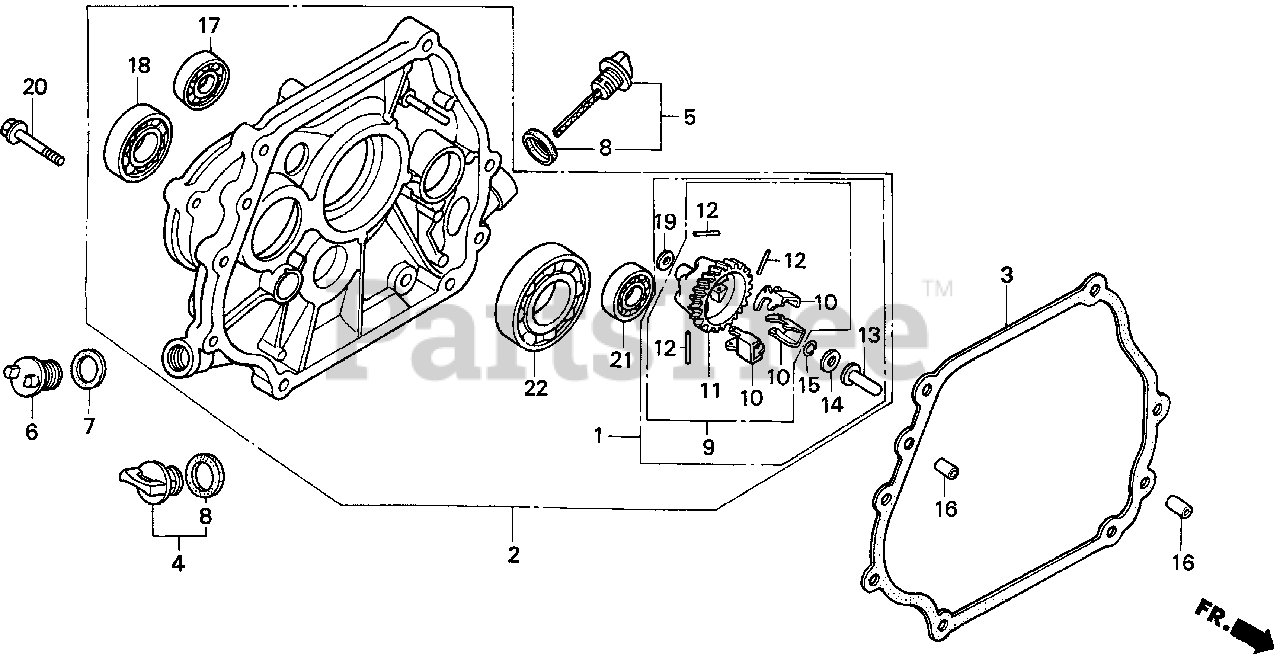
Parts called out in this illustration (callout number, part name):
1	GOVERNOR KIT
2	COVER ASSY., CRANKCASE
3	GASKET, CASE COVER
4	CAP ASSY., OIL FILLER
5	CAP ASSY., OIL FILLER
6	CAP, OIL FILLER
7	GASKET, OIL FILLER CAP
8	GASKET, OIL FILLER CAP
9	GOVERNOR ASSY.
10	WEIGHT, GOVERNOR
11	HOLDER, GOVERNOR WEIGHT
12	PIN, GOVERNOR WEIGHT
13	SLIDER, GOVERNOR
14	WASHER (6X16)
15	CLIP, GOVERNOR HOLDER
16	PIN, DOWEL (8X12)
17	BEARING, RADIAL BALL (6202)
18	BEARING, RADIAL BALL (6204) (TOYO)
19	WASHER, PLAIN (6MM)
20	BOLT, FLANGE (8X40)
21	BEARING, RADIAL BALL (6202)
22	BEARING, RADIAL BALL (6207)
